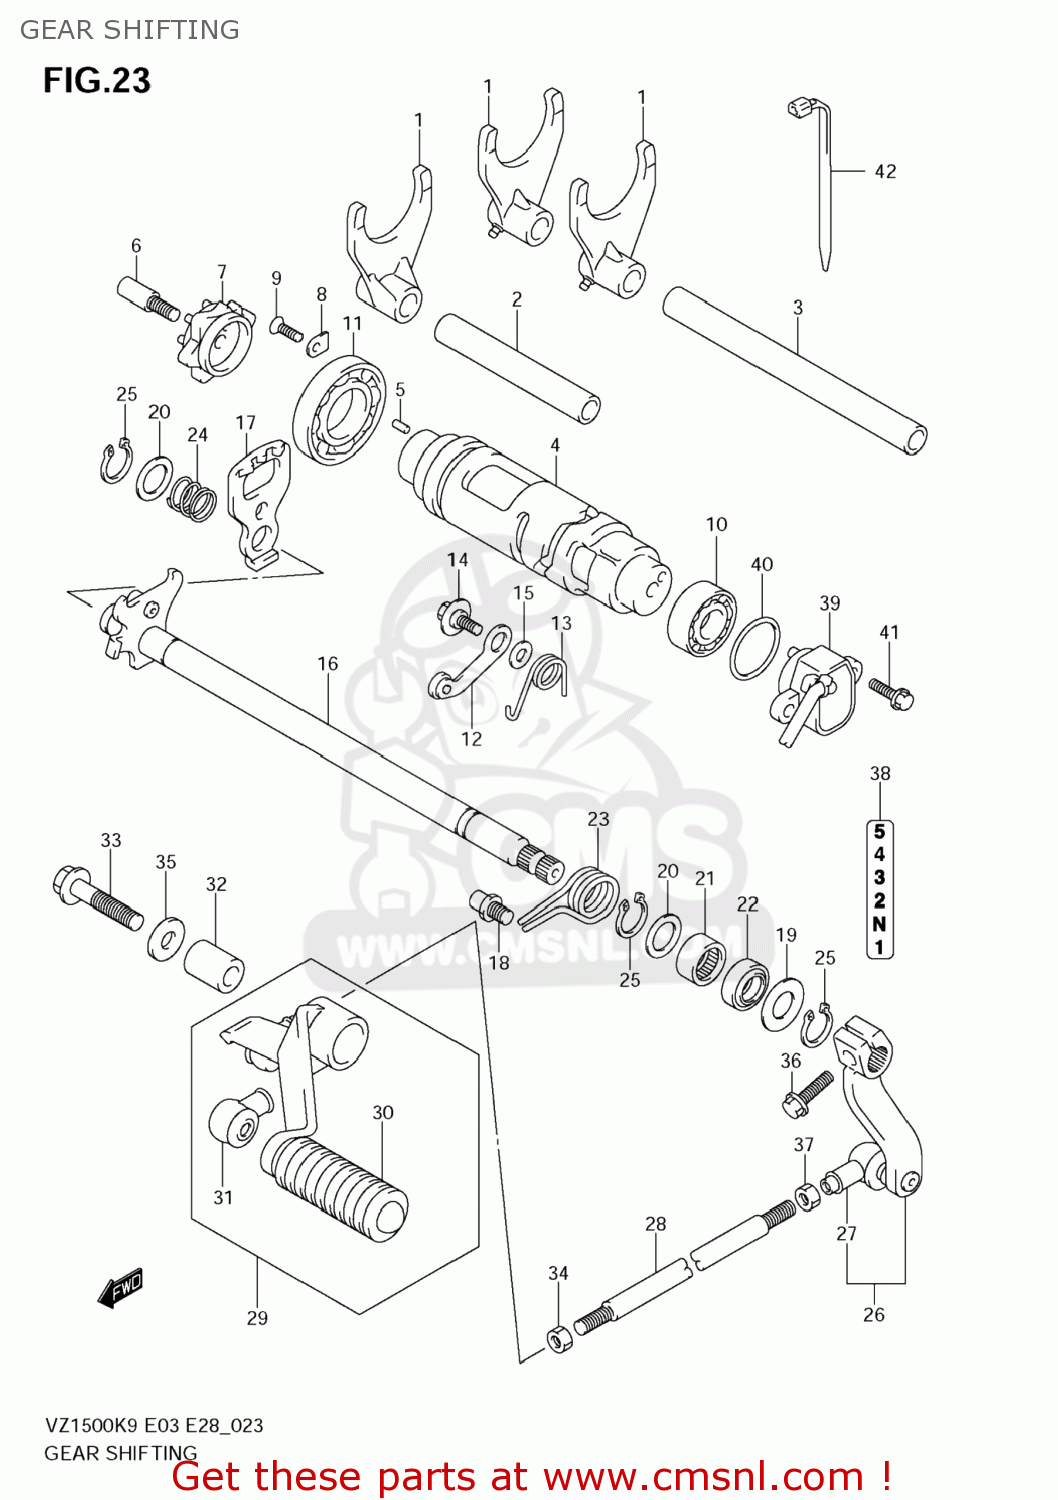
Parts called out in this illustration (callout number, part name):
1	FORK,GEAR SHIFT NO.1
2	SHAFT,GEAR SHIFT FORK(L:152)
3	SHAFT,GEAR SHIFT FORK NO.1
4	CAM,GEAR SHIFT
5	PIN
6	BOLT,GEAR SHIFT CAM PLATE
7	PLATE,GEAR SHIFT CAM
8	RETAINER,COUNTER BEARING,R
9	SCREW(6X12)
10	BEARING
11	BEARING(25X32X12)
12	STOPPER,SHIFT CAM
13	SPRING,STOPPER ARM
14	BOLT(6X14.3)
15	WASHER
16	SHAFT,GEAR SHIFT
17	PLATE,GEAR SHIFT CAM DRIVE
18	STOPPER,GEAR SHIFT ARM
19	WASHER(14X29X0.8)
20	SHIM(14X22X1)
21	BEARING(14X20X12)
22	SEAL,OIL(14X22X6)
23	SPRING
24	SPRING
25	CIRCLIP
26	ARM,GEAR SHIFT LINK
27	COVER,DUST
28	ROD,GEAR SHIFT LINK
29	LEVER ASSY,GEAR SHIFT
30	RUBBER,GEAR SHIFT PEDAL
31	COVER,DUST
32	SPSCER,GEAR SHIFT LEVER
33	BOLT(10X40)
34	NUT
35	WASHER(10.5X24X2.3)
36	BOLT
37	NUT
38	LABEL,GEAR SHIFT
39	SENSOR ASSY,GE
40	O RING(D:2.4,ID:26.2)
41	BOLT
42	CLAMP(L:125)
